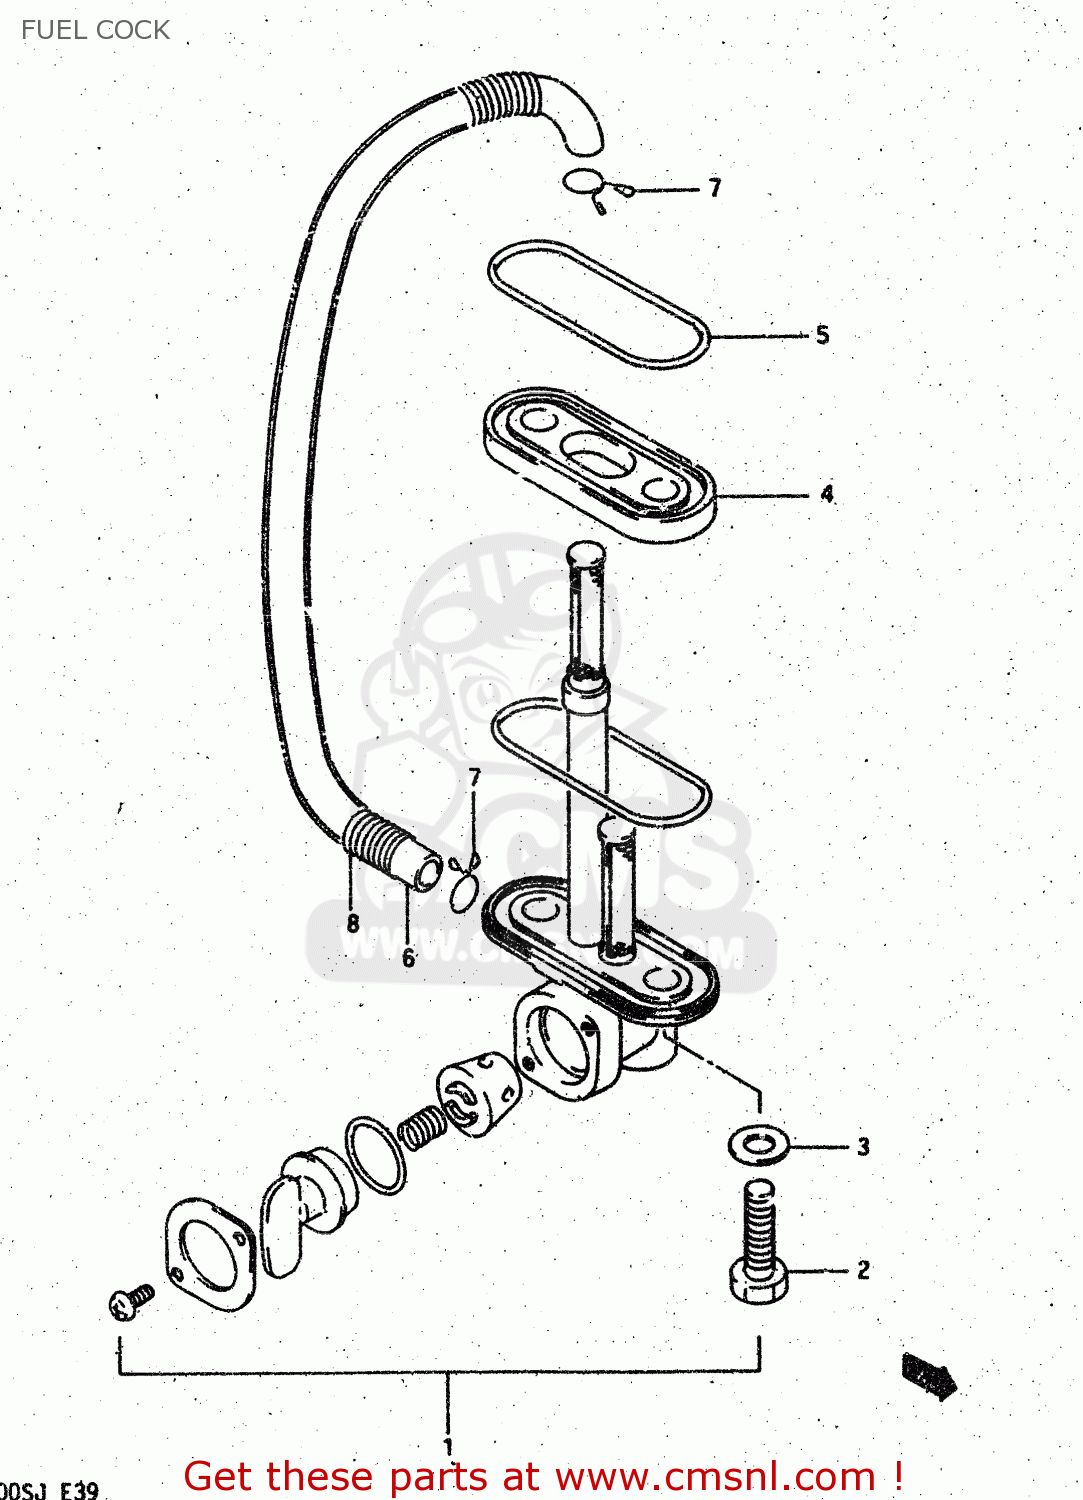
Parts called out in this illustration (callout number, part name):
1	COCK ASSY,FUEL
2	BOLT(6X20)
3	GASKET
4	SPACER,FUEL COCK
5	GASKET,FUEL COCK (NAS)
6	HOSE
7	CLIP
8	SPRING
